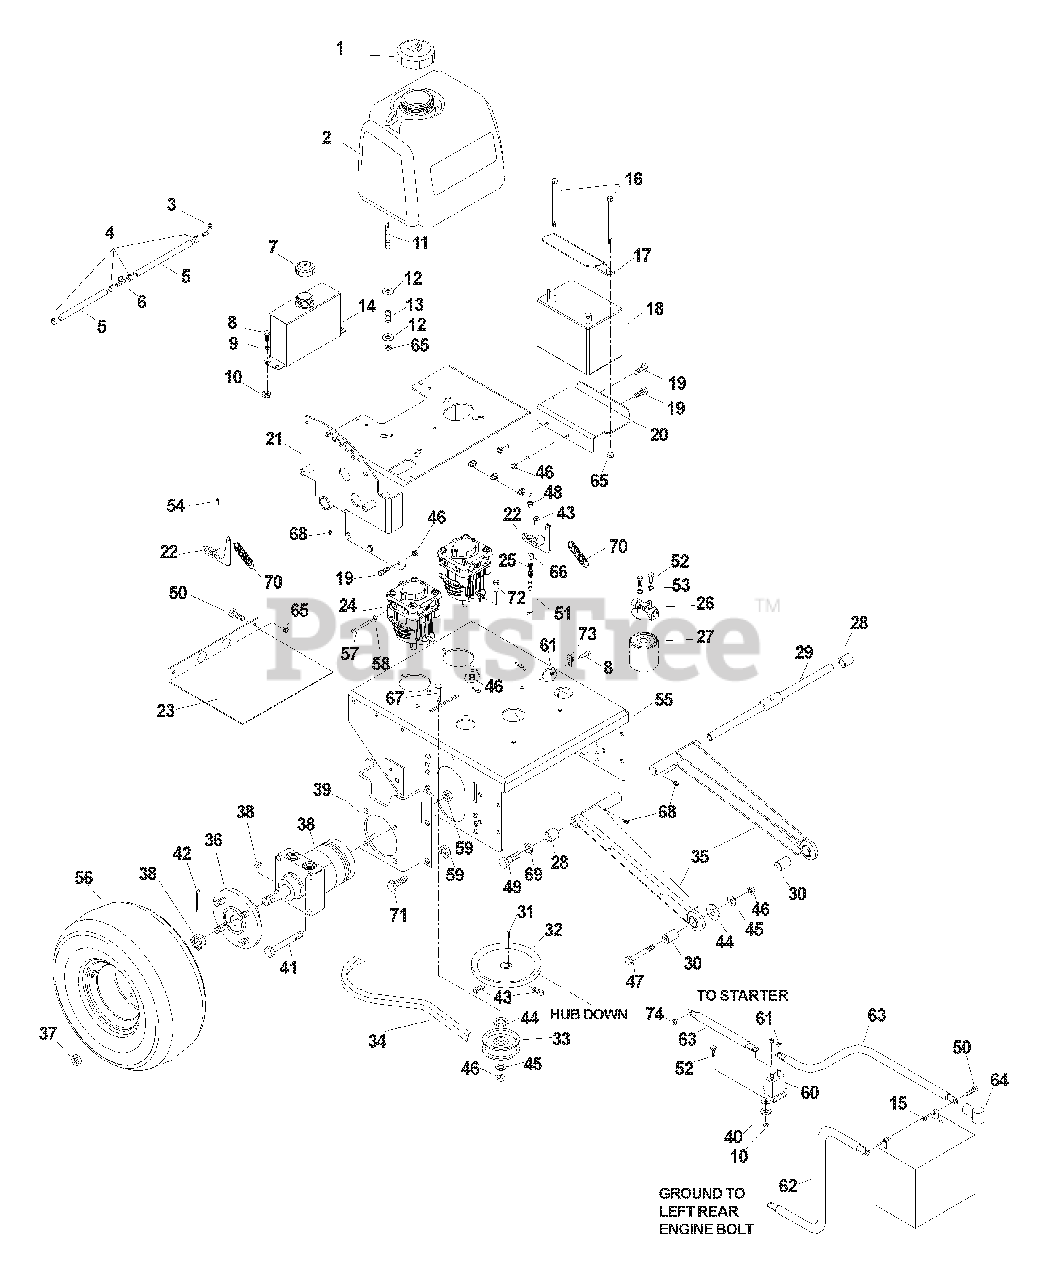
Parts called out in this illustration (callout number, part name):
1	FUEL CAP
3	FUEL FITTING
4	HOSE CLAMP
6	FUEL VALVE
8	HCS, 1/4C X 3/4
9	WASHER, 1/4
10	NUT, 1/4, CENTER LOCK
12	WASHER, 5/16
15	NUT, 5/16, CENTER LOCK
16	HCS, 5/16C X 7
17	BATTERY STRAP
18	BATTERY, DRY
19	HCS, 3/8C X 3/4
20	BATTERY TRAY
21	TANK SUPPORT
23	BELT SHIELD
24	PUMP W/POPPETS
26	FILTER HEAD
29	STRUT SHAFT
30	SPACER, FRONT
31	KEY, METRIC
33	IDLER PULLEY
38	HYD. MOTOR
39	MOTOR MOUNT
40	IT LOCKWASHER, 1/4
41	HCS 1/2C X 2 3/4
42	COTTER PIN
43	SET SCR. 5/16 X 5/8
44	WASHER, 1/2
45	WASHER, 3/8
46	NUT, 3/8, CENTER LOCK
47	HCS, 3/8C X 2 1/4
48	NUT, 3/8C, NYLOC
49	HCS, 1/2 X 1
50	HCS, 5/16C X 3/4
51	HCS, 3/8C X 2 3/4
52	HCS, 1/4C X 5/8
53	LOCKWASHER, 1/4
54	SET SCREW, 5/16-18 X 5/8
56	TIRE /WHEEL ASM.
56	RIM
57	CLEVIS PIN
59	NUT, 1/2C, NYLOC
61	NUT, 1/4, NYLOC
62	NEGATIVE CABLE
63	POSITIVE CABLE
65	NUT, 5/16C, NYLOC
67	RHSNB, 3/8C X 2
68	ZERK
69	LOCKWASHER, 1/2
70	SPRING, PUMP
71	HFCS, 1/2C X 1 1/4
72	HCS, 3/8C X 1
74	NUT, 1/4, THIN NYLOC
